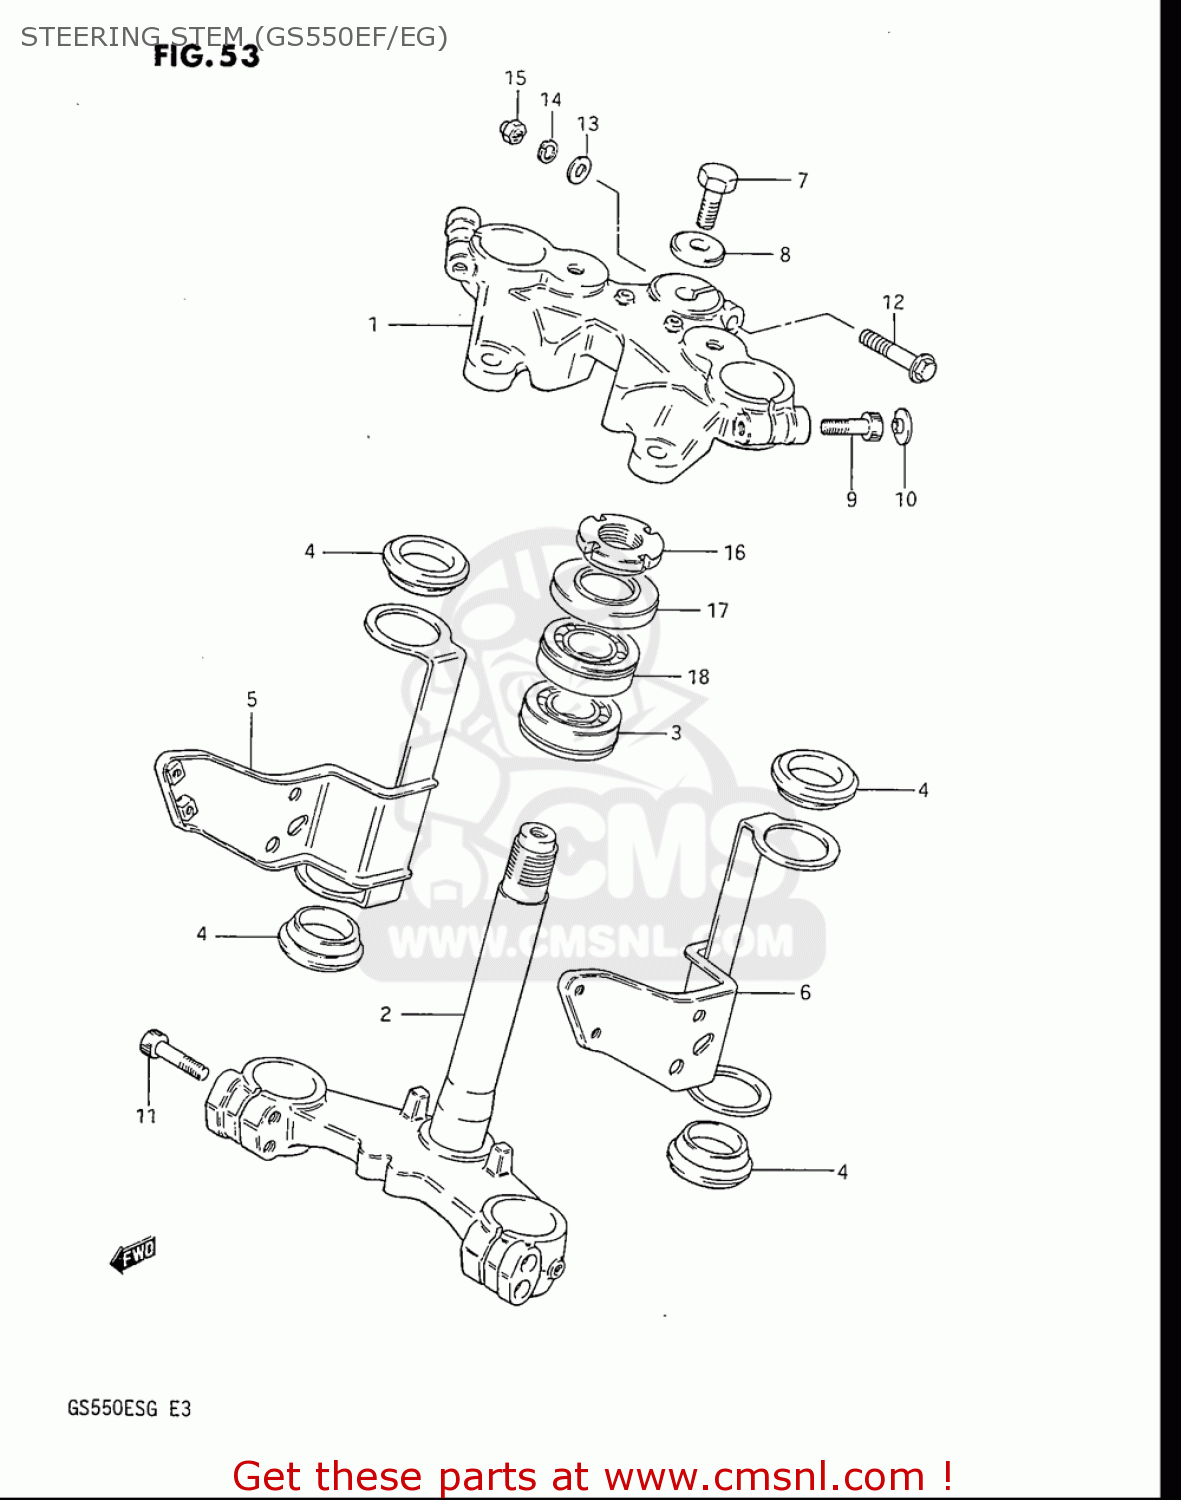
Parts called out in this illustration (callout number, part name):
3	BEARING(30X55X17)
4	CUSHION,HEADLAMP BRACKET
5	BRACKET SET,HEADLAMP
7	BOLT,STEERING STEM HEAD
8	WASHER,STEERING STEM
9	BOLT,FORK INNER TUBE FITTING
10	CAP(OD:20)
11	BOLT
12	BOLT
13	WASHER
14	WASHER,LOCK
15	NUT
16	NUT,STEERING STEM
17	DUST SEAL,STEERING UPR
18	BEARING(25X47X15)
